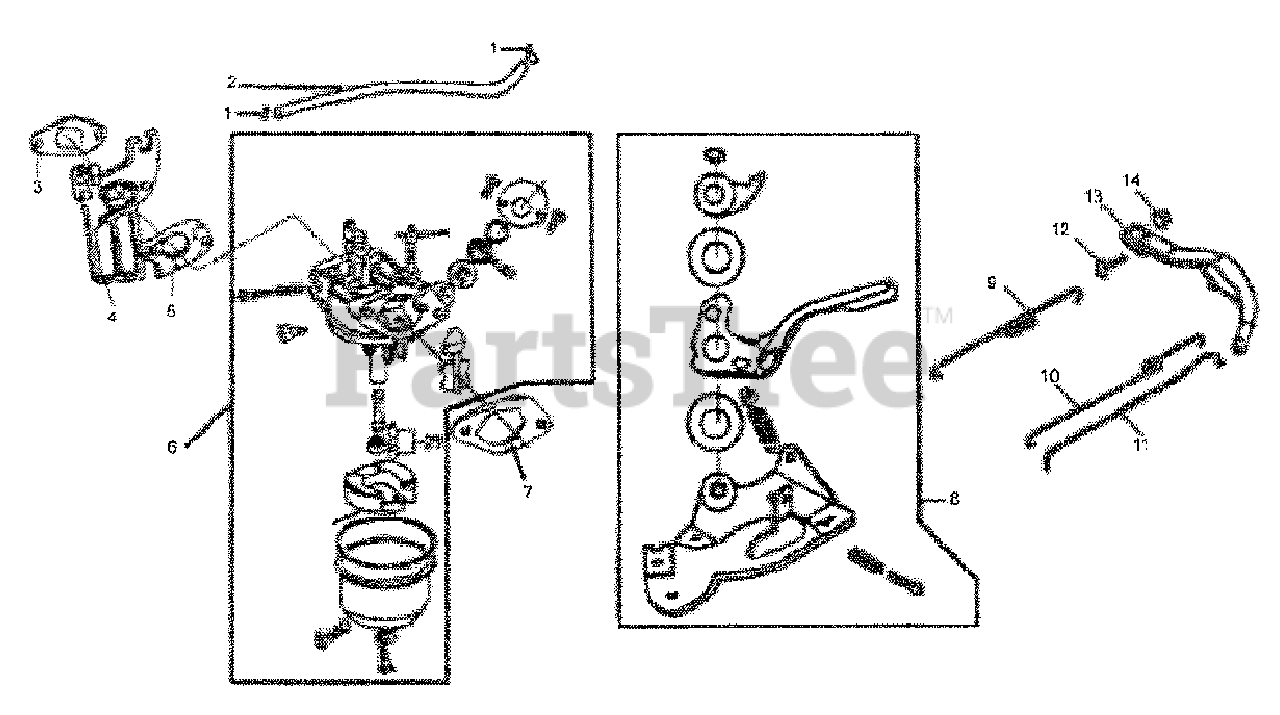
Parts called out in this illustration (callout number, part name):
2	HOSE' FUEL' M4.5X170
3	GASKET' INTAKE
4	BLOCK' CONNECTING
5	GASKET' CARBURETOR
6	CARBURETOR ASSY
7	GASKET' AIR CLEANER
8	REGULATOR ASSY
9	SPRING' BACK
10	SPRING' REGULATING
11	ROD' PULLING
12	BOLT' LOCK
13	ARM' REGULATING
